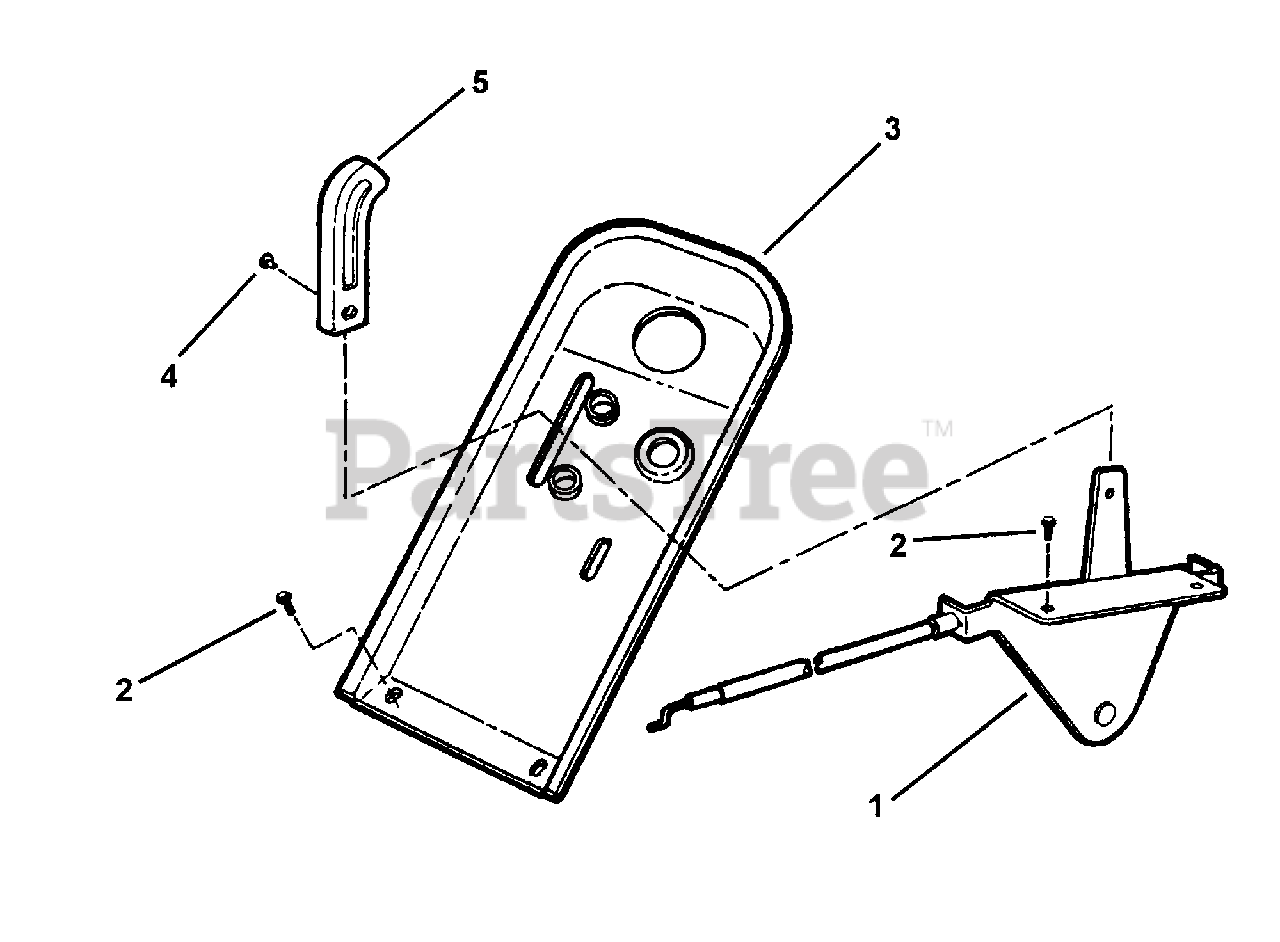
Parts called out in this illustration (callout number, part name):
1	CONTROL, Throttle
2	SCREW, #10-24 x 1/2" Hex Washer Self-Tap (Torx)
3	COVER, Dash Panel (Electric Start)
4	RIVET, Plastic Snap
5	KNOB, Throttle Control
